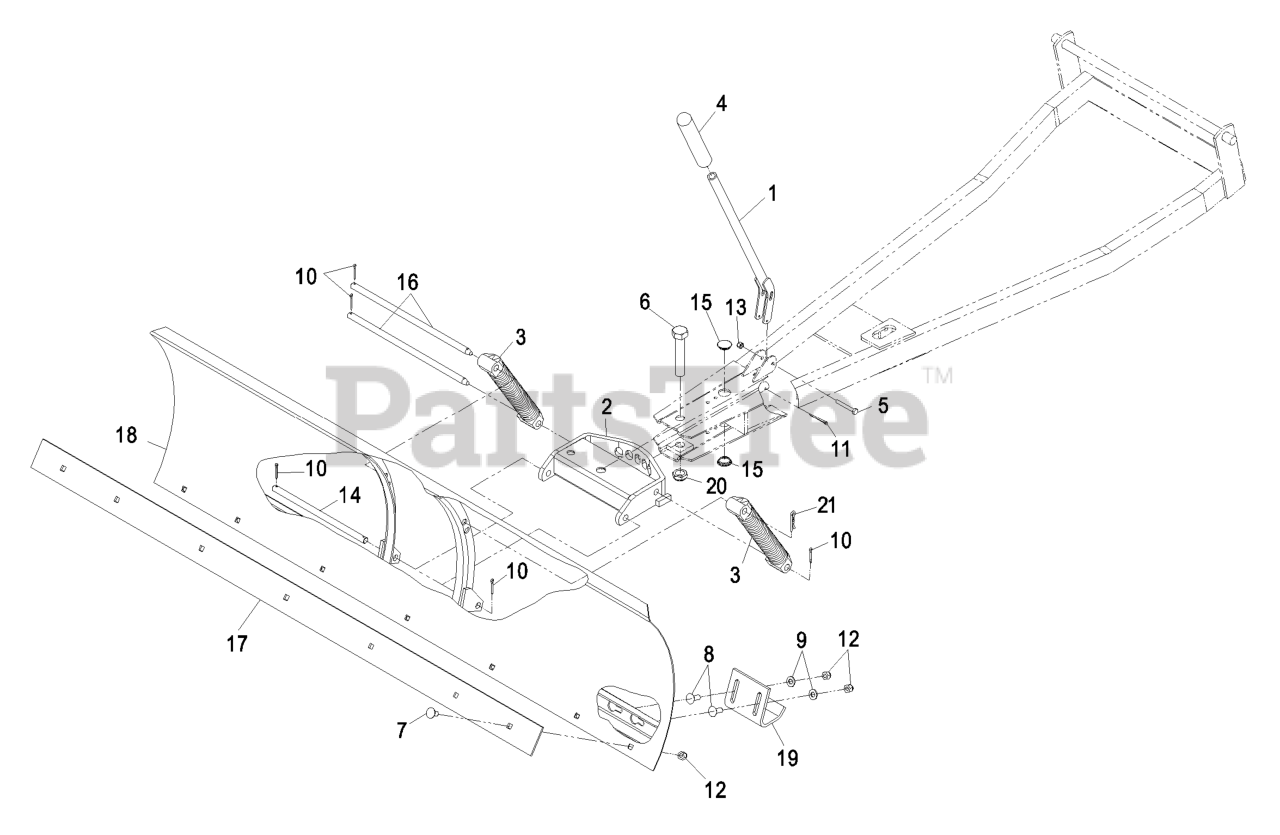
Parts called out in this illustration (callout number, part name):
1	LEVER-INDEX
3	LUG / SPRING ASM
4	GRIP-HANDLE
5	SCREW-HH
6	SCREW-HH
7	SCREW-HH
8	BOLT-CARR
9	WASHER-FLAT
10	PIN-COTTER
11	PIN-COTTER
12	NUT-LOCK, NI
13	NUT-LOCK, NI
14	ROD-LOWER
16	ROD-PIVOT, BLADE
17	PLATE-BLADE EDGE
18	BLADE ASM-56"
21	PIN-HAIR
